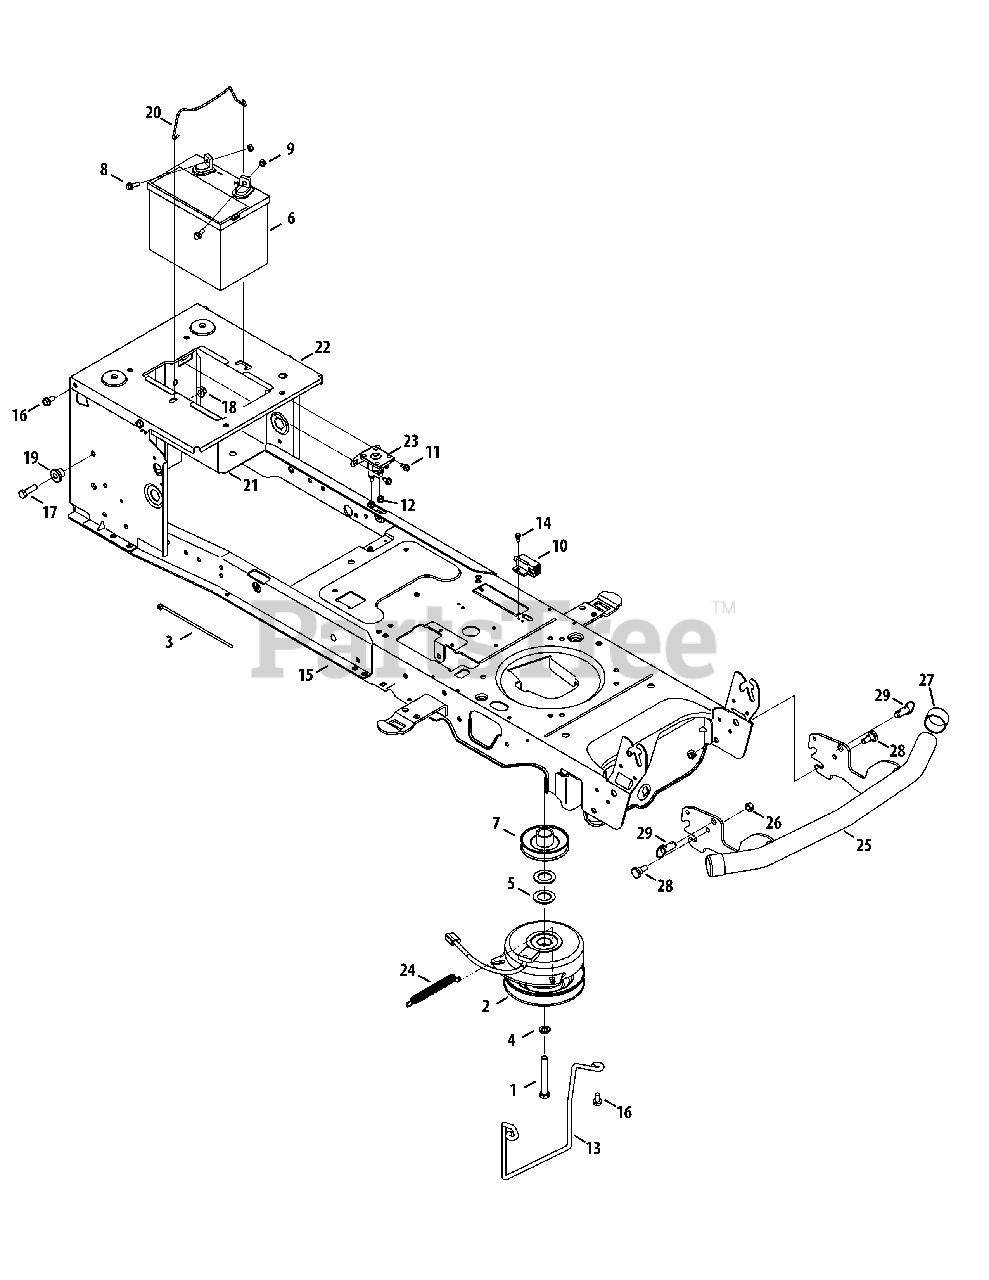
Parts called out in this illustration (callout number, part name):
1	Hex Screw, 7/16-20, 3.50, Gr5, Lock
2	Clutch, Electric PTO
3	Cable, Tie, 3/16 X .05 X 7.4
4	Washer, Lock, 7/16 , Regular Duty
5	Washer, Flat, 1.031 X1.620 X.095
7	Engine Pulley, Electric PTO
8	Hex Flange Screw, 1/4-20, .75, Gr5
9	Nut, Sems, 1/4-20
10	Switch, Interlock
11	Screw, Self-tapping, 1/4-20, 0.375
12	Nut, Flange Lock, 1/4-20, Nylon
13	Rod, Keeper
14	Screw, Shoulder, #10-32, .50
15	Frame Assembly, Lower
16	Screw, Self-tapping, 5/16-18, .750
17	Hex Screw, 3/8-16, 1.50, Gr2
18	Nut, Flange Lock, 3/8-16, Nylon
19	Spacer, Shoulder, .38 X 1.0 X .70
20	Rod, Battery
21	Tray, Battery
23	Solenoid, 12V, 100 Amp, 4 term
24	Spring, Extn, .56 Dia X 5.52
26	Nut, Hex Lock, 3/8-16, GrB
27	Cap, Bumper
28	Bolt, Shoulder, .496 x .336, 3/8-16
29	Pin, Quick Release, 1/2 Dia x .50
